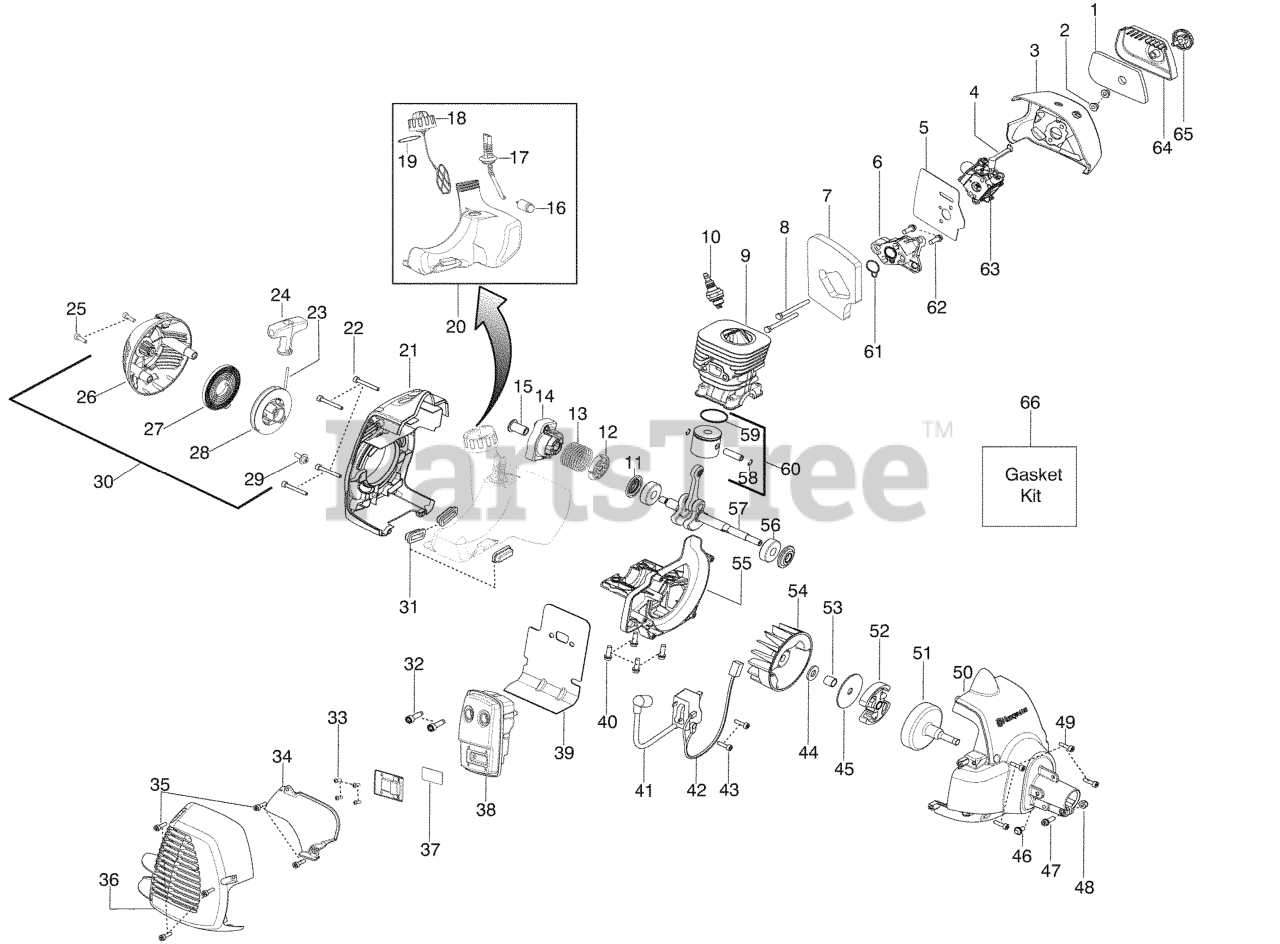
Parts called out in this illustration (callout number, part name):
1	FILTER AIRBOX
3	RP_AIR BOX
4	CHOKE LEVER
5	KIT GASKET CARB
6	CARB ADAPTOR
7	KIT GASKET 28CC
8	BOLT CARB ADAPTOR
9	CYLINDER
10	Plug-Spark (RCJ-8Y)
11	KIT SEAL CRANKSHAFT
12	WASHER STARTER
13	SPRING STARTER CUP
14	ASSY STARTER CUP
15	COUPLING STARTER
16	FUEL PICK-UP ASSY
17	KIT FUEL LINE
18	ASSY-CAP W/RETAINER
19	KIT GASKET 28CC
20	FUEL TANK ASSY
21	REAR SHROUD
24	STARTER HANDLE GRAY
25	SCREW M5-0.8X30MM
26	STARTER HOUSING
27	%KIT STARTER SPRING
28	KIT STARTER PULLEY
30	ASSY-STARTER HSG.
31	ISOLATOR FUEL TANK
32	BOLT MUFFLER
33	SCREW-10-16 X 1/2 HI-LO
34	SHIELD HEAT
35	SCREW M4 X 1.75 PT 16MM
36	GUARD-MUFFLER
37	KIT SPARK ARRESTOR SCREEN
38	ASSY-MUFFLER
39	KIT GASKET 28CC
40	SCREW-M5-0.8 X 25MM(TAP)
41	IGNITION MODULE MBU-7
42	ASSY MODULE LEAD WIRE
43	SCREW M4 X .70 TT 16MM
44	WASHER CLUTCH
45	WASHER-CLUTCH
48	LOCKNUT-HEX 10-24
49	SCREW M4 X .70 TT 16MM
50	FAN HSG ASSY
51	Assy-Clutch Drum
52	%KIT CLUTCH ASSY
53	SPACER FLYWHEEL
55	CRANKCASE CASTING
56	BEARING RADIAL BALL (6201)
57	KIT CRANKSHAFT ASSY
58	WRIST PIN RET.
59	RING PISTON
60	KIT PISTON 28CC TRIMMER
61	KIT GASKET 28CC
62	SCREW-M5-0.8 X 25MM(TAP)
63	Kit-Carb.
64	COVER-AIR BOX
65	KNOB ASSY AIRBOX COVER
66	KIT GASKET 28CC
